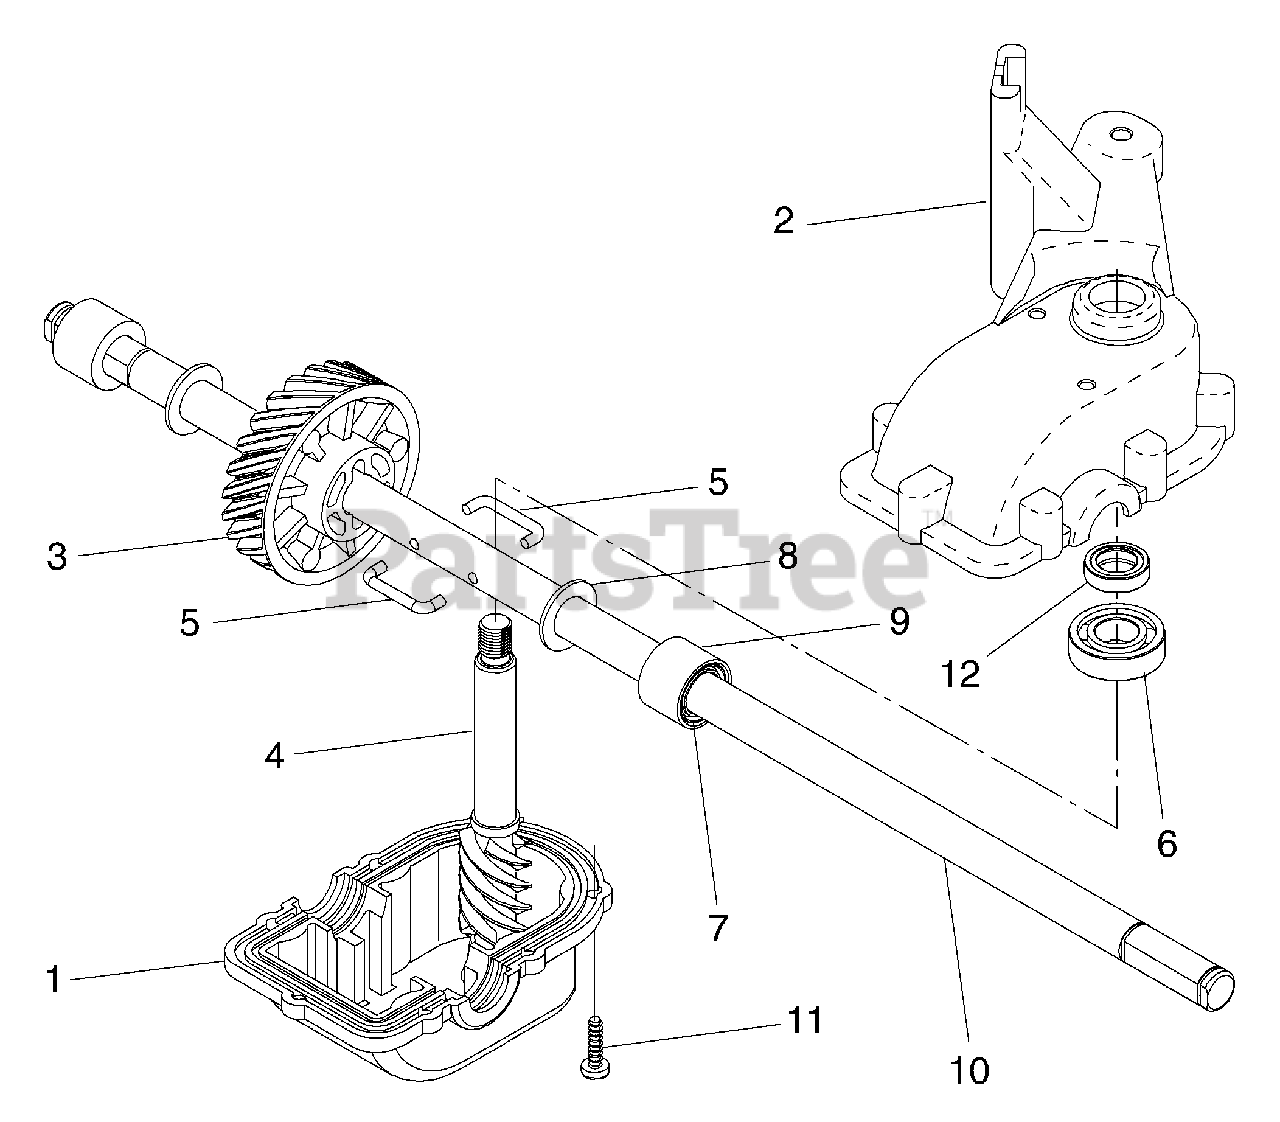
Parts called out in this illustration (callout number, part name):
1	Case, Lower
2	Case, Upper
3	Gear, 24 Teeth
4	Shaft, Input
5	Wire, Formed
6	Bearing, Ball
7	Seal, Output Shaft
10	Shaft, Output
12	Seal, Input Shaft
